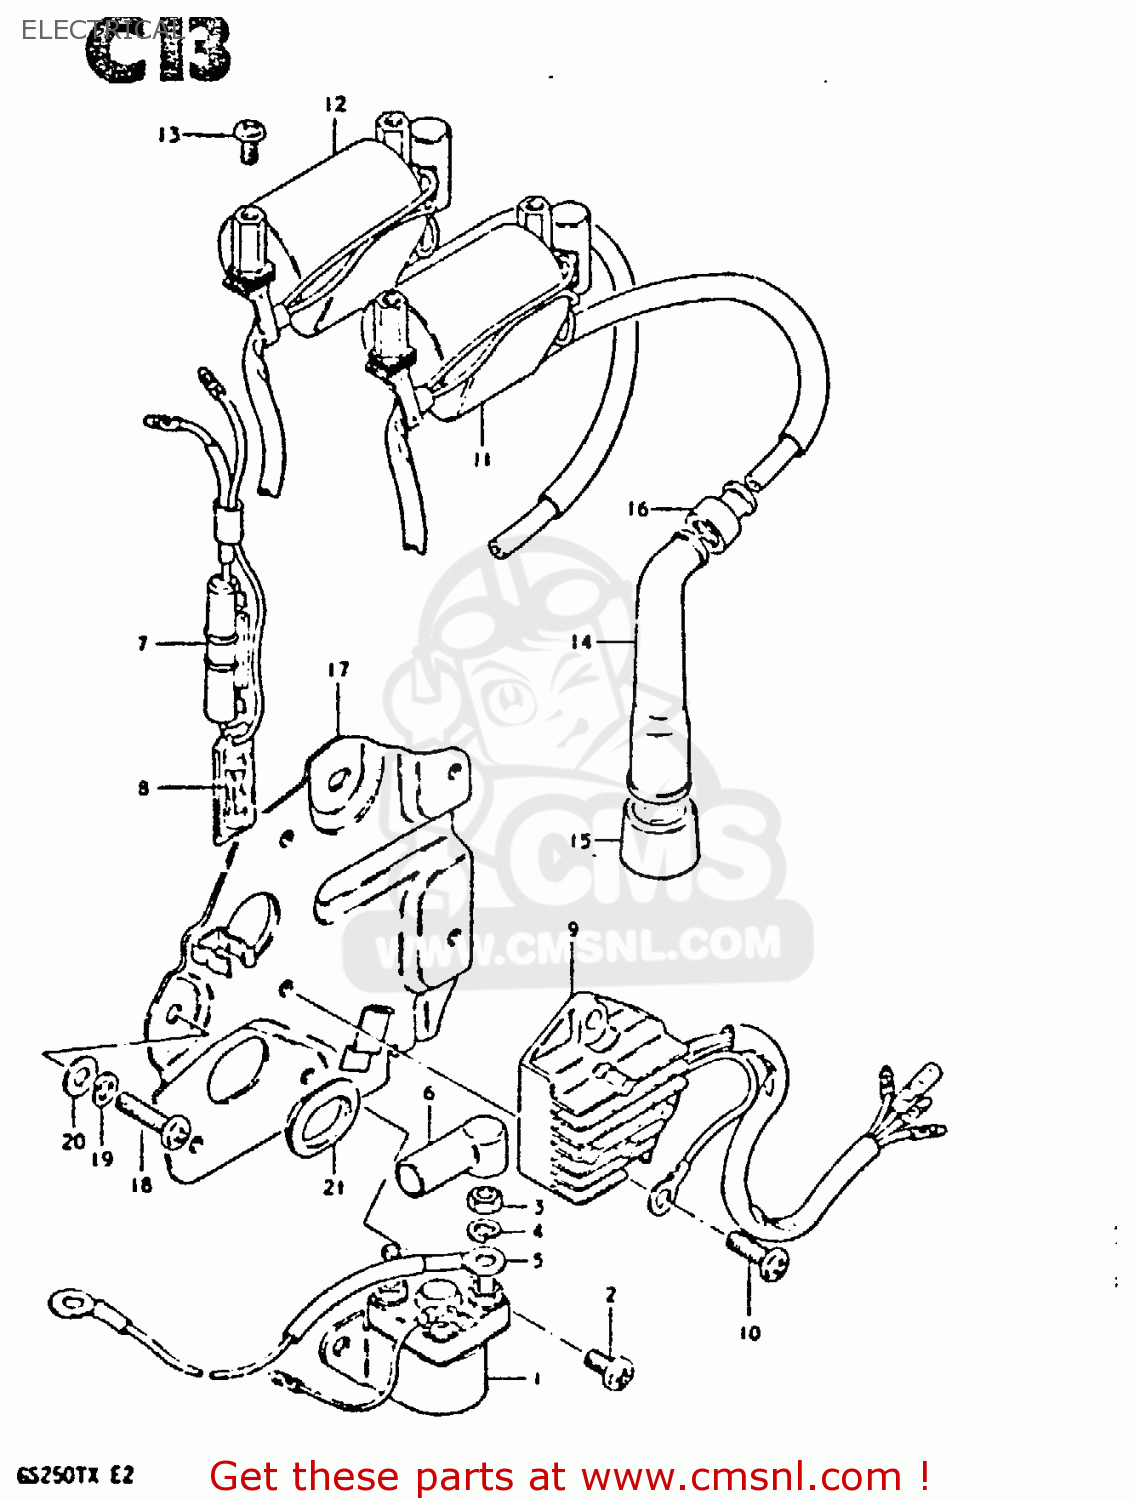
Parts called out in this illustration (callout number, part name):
1	RELAY ASSY,STARTING MOTOR
2	SCREW
3	NUT 6MM
4	LOCK WASHER
5	CORD,BATTERY MINUS
6	CAP,STARTER RELAY
7	BOX ASSEMBLY,FUSE
8	FUSE(15A)
9	RECTIFIER ASSEMBLY
10	SCREW
11	COIL ASSEMBLY,IGNITION
12	COIL ASSEMBLY,IGNITION
13	SCREW
14	CAP,SPARK PLUG
15	SEAL,SPARK PLUG
16	SEAL,SPARK PLU
17	PLATE,ELECTRIC PARTS H
18	SCREW
19	LOCK WASHER
20	WASHER
21	GROMMET
